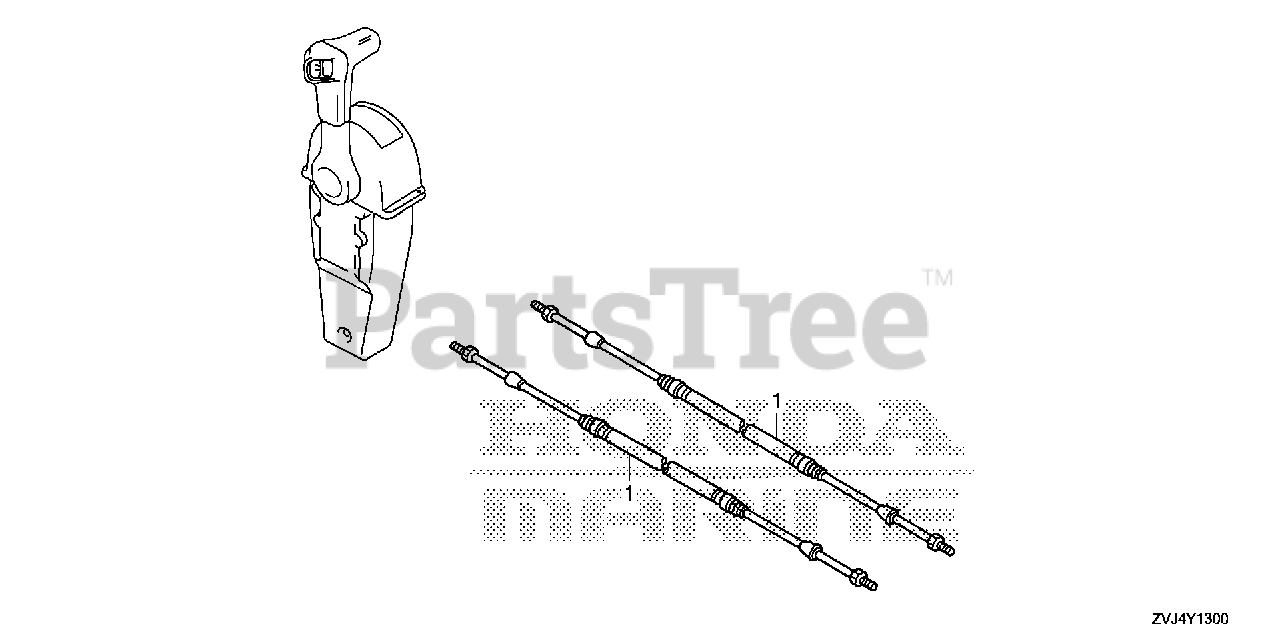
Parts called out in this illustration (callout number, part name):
1	CABLE, REMOTE CONTROL (10') (LOW FRICTION)
1	CABLE ASSY., PUSH-PULL (33C-5FT)
1	CABLE, REMOTE CONTROL (11') (LOW FRICTION)
1	CABLE ASSY., PUSH-PULL (33C-6FT)
1	CABLE, REMOTE CONTROL (12') (LOW FRICTION)
1	CABLE ASSY., PUSH-PULL (33C-7FT)
1	CABLE, REMOTE CONTROL (13') (LOW FRICTION)
1	CABLE ASSY., PUSH-PULL (33C-8FT)
1	CABLE, REMOTE CONTROL (14') (LOW FRICTION)
1	CABLE ASSY., PUSH-PULL (33C-9FT)
1	CABLE, REMOTE CONTROL (15') (LOW FRICTION)
1	CABLE ASSY., PUSH-PULL (33C-10FT)
1	CABLE, REMOTE CONTROL (16') (LOW FRICTION) (NOT AVAILABLE)
1	CABLE ASSY., PUSH-PULL (33C-11FT)
1	CABLE, REMOTE CONTROL (17') (LOW FRICTION)
1	CABLE ASSY., PUSH-PULL (33C-12FT)
1	CABLE, REMOTE CONTROL (18') (LOW FRICTION) (NOT AVAILABLE)
1	CABLE ASSY., PUSH-PULL (33C-13FT)
1	CABLE, REMOTE CONTROL (19') (LOW FRICTION)
1	CABLE ASSY., PUSH-PULL (33C-14FT)
1	CABLE, REMOTE CONTROL (20') (LOW FRICTION) (NOT AVAILABLE)
1	CABLE ASSY., PUSH-PULL (33C-15FT)
1	CABLE, REMOTE CONTROL (21') (LOW FRICTION)
1	CABLE ASSY., PUSH-PULL (33C-16FT)
1	CABLE, REMOTE CONTROL (22') (LOW FRICTION) (NOT AVAILABLE)
1	CABLE ASSY., PUSH-PULL (33C-17FT)
1	CABLE, REMOTE CONTROL (23') (LOW FRICTION)
1	CABLE ASSY., PUSH-PULL (33C-18FT)
1	CABLE, REMOTE CONTROL (24') (LOW FRICTION) (NOT AVAILABLE)
1	CABLE ASSY., PUSH-PULL (33C-19FT)
1	CABLE, REMOTE CONTROL (25') (LOW FRICTION)
1	CABLE ASSY., PUSH-PULL (33C-20FT)
1	CABLE, REMOTE CONTROL (26') (LOW FRICTION)
1	CABLE ASSY., PUSH-PULL (33C-21FT)
1	CABLE, REMOTE CONTROL (27') (LOW FRICTION)
1	CABLE ASSY., PUSH-PULL (33C-22FT)
1	CABLE, REMOTE CONTROL (28') (LOW FRICTION) (NOT AVAILABLE)
1	CABLE ASSY., PUSH-PULL (33C-23FT)
1	CABLE, REMOTE CONTROL (29') (LOW FRICTION)
1	CABLE ASSY., PUSH-PULL (33C-24FT)
1	CABLE, REMOTE CONTROL (30') (LOW FRICTION) (NOT AVAILABLE)
1	CABLE ASSY., PUSH-PULL (33C-25FT)
1	CABLE, REMOTE CONTROL (31') (LOW FRICTION)
1	CABLE ASSY., PUSH-PULL (33C-26FT)
1	CABLE, REMOTE CONTROL (32') (LOW FRICTION) (NOT AVAILABLE)
1	CABLE ASSY., PUSH-PULL (33C-27FT)
1	CABLE, REMOTE CONTROL (33') (LOW FRICTION)
1	CABLE ASSY., PUSH-PULL (33C-28FT)
1	CABLE, REMOTE CONTROL (34') (LOW FRICTION) (NOT AVAILABLE)
1	CABLE ASSY., PUSH-PULL (33C-29FT)
1	CABLE, REMOTE CONTROL (35') (LOW FRICTION)
1	CABLE ASSY., PUSH-PULL (33C-30FT)
1	CABLE ASSY., PUSH-PULL (33C-31FT)
1	CABLE ASSY., PUSH-PULL (33C-32FT)
